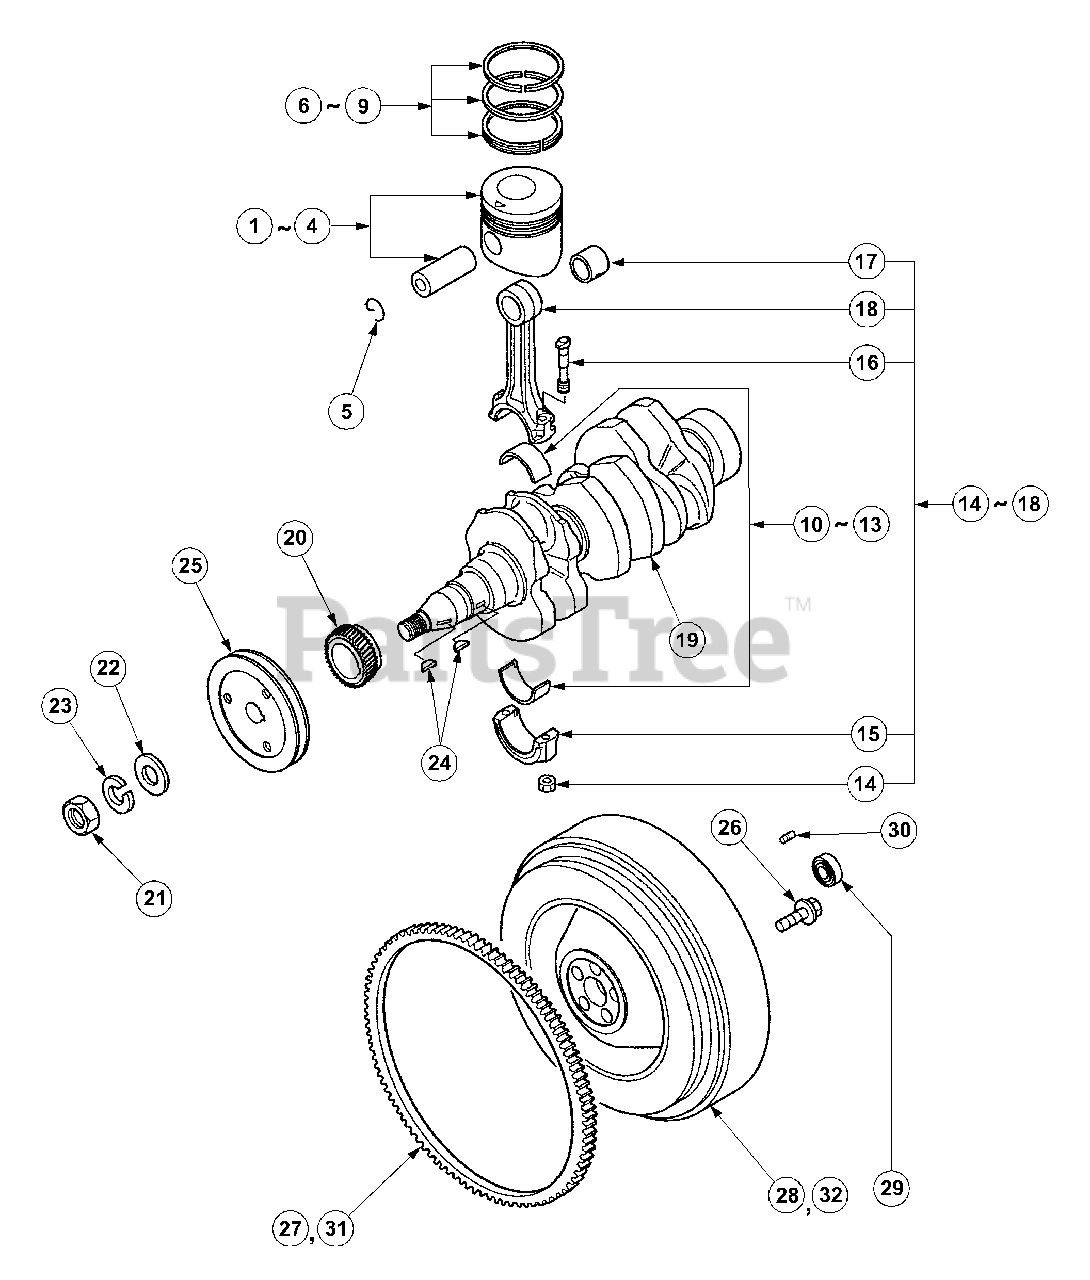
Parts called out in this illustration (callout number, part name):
1	Piston,Pin Set
2	Piston,Pin Set
3	Piston,Pin Set
4	Piston,Pin Set
5	Clip,Piston Pin
6	Ring Set,Piston
7	Ring Set,Piston
8	Ring Set,Piston
9	Ring Set,Piston
10	Bearing Set
11	Bearing Set
12	Bearing Set
13	Bearing Set
14	Nut,Con Rod
15	Cap
16	Bolt,Con Rod
18	Con Rod
19	Crankshaft
20	Gear,Crankshaft
23	Washer,Spring
26	Bolt
28	Flywheel
29	Bearing,Ball
32	Flywheel
